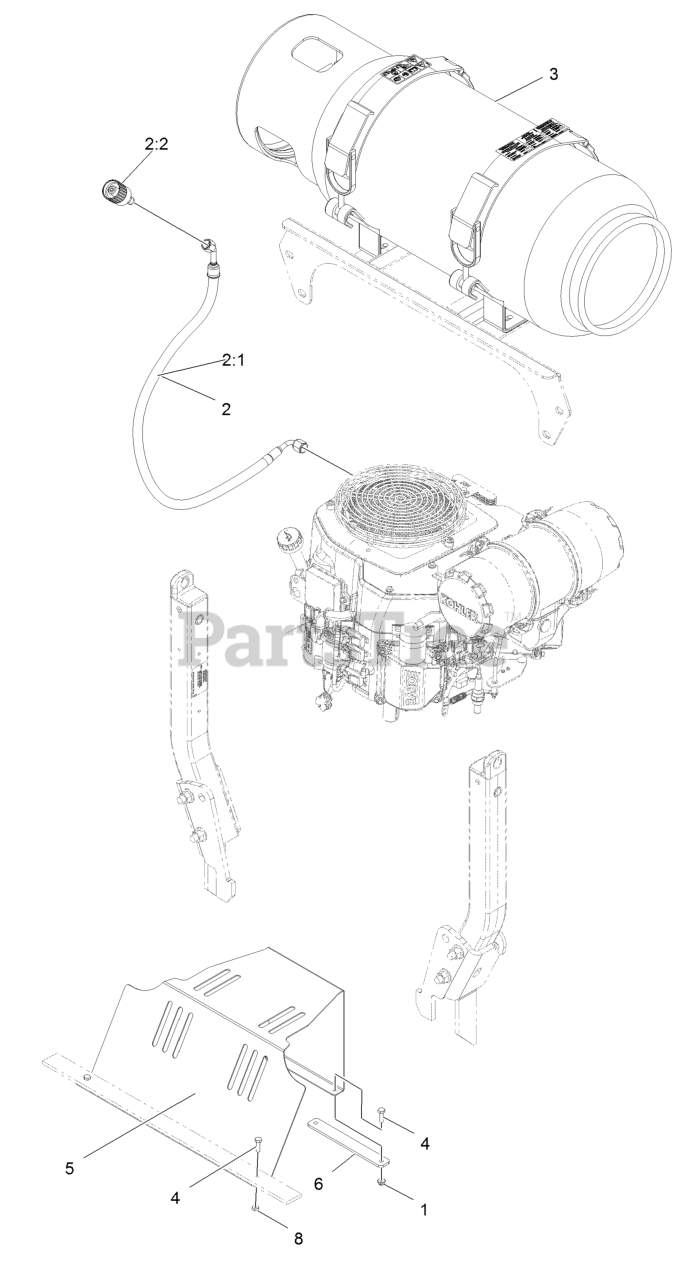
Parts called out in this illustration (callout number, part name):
1	Nut-Nyloc 1/4-20 Flg
2	LPG Hose ASM
2:1	Hose ASM, LPG
2:2	Connector-LP, Straight
3	Tank-LPG
4	Screw-HH 1/4-20 X 7/8
5	Sheild-Fan
8	Nut-Jam 1/4-20
